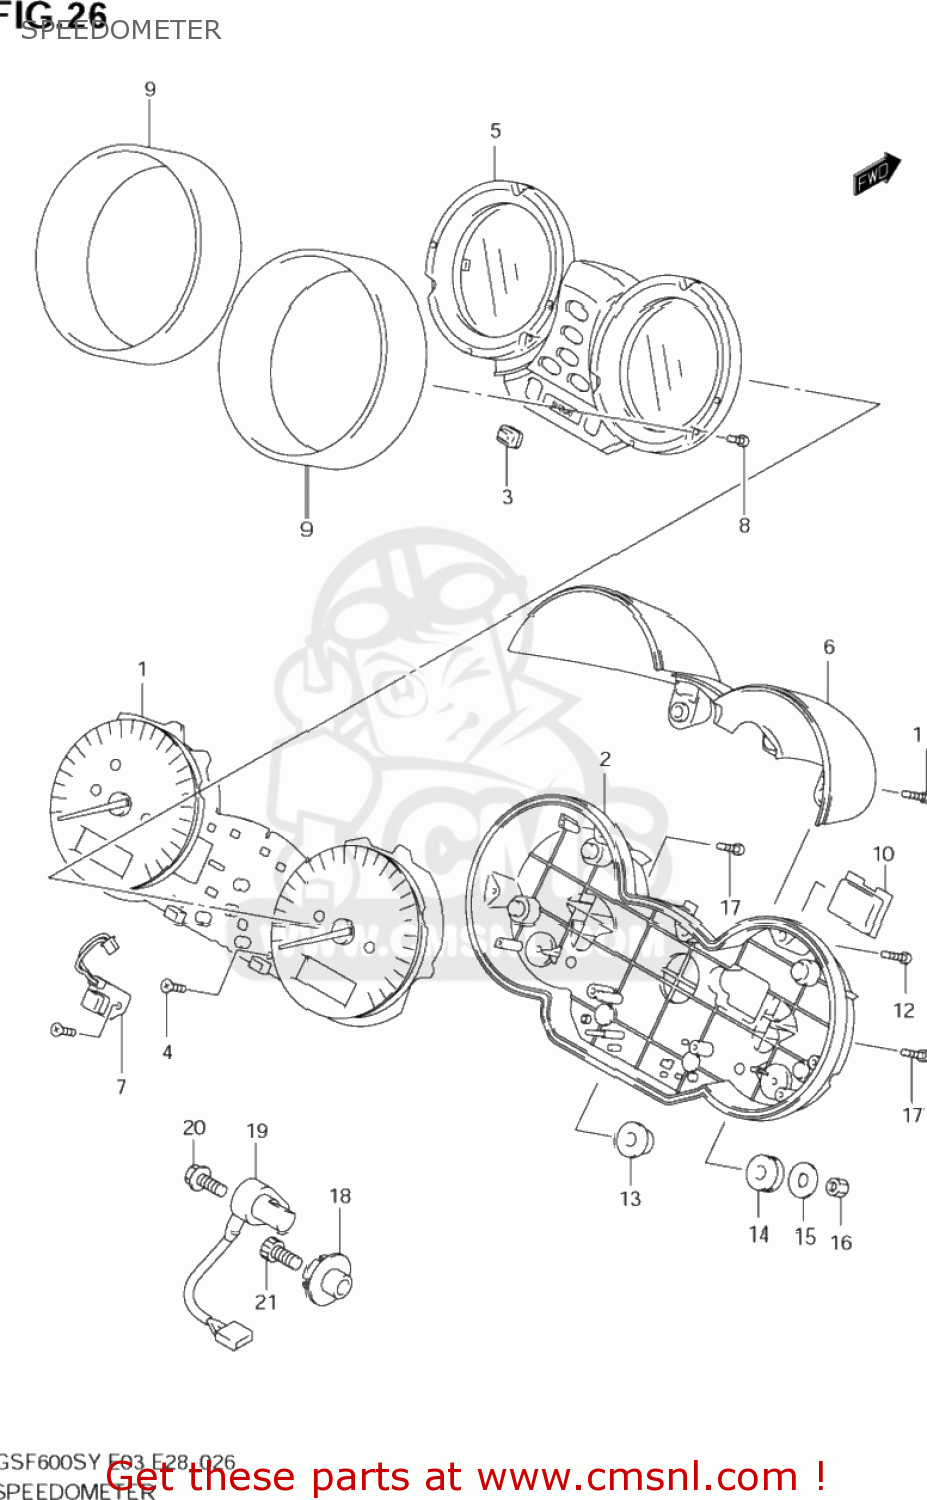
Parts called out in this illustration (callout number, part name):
1	SPEEDOMETER
2	CASE ASSY,LWR
3	RUBBER,SWITCH
4	SCREW(4X14)
5	UPR CASE ASSY
6	COVER
7	SWITCH,PRINT CIRCUIT
8	SCREW(2.3X8)
9	RING
10	GROMMET
11	SCREW,PAN HEAD(3X14)
12	SCREW(3X16)
13	CUSHION
14	CUSHION
15	WASHER(5.5X16X1.2)
16	NUT
17	SCREW,PAN HEAD(3X16)
18	ROTOR,SPEED
19	SENSOR,SPEED
20	BOLT
21	BOLT
